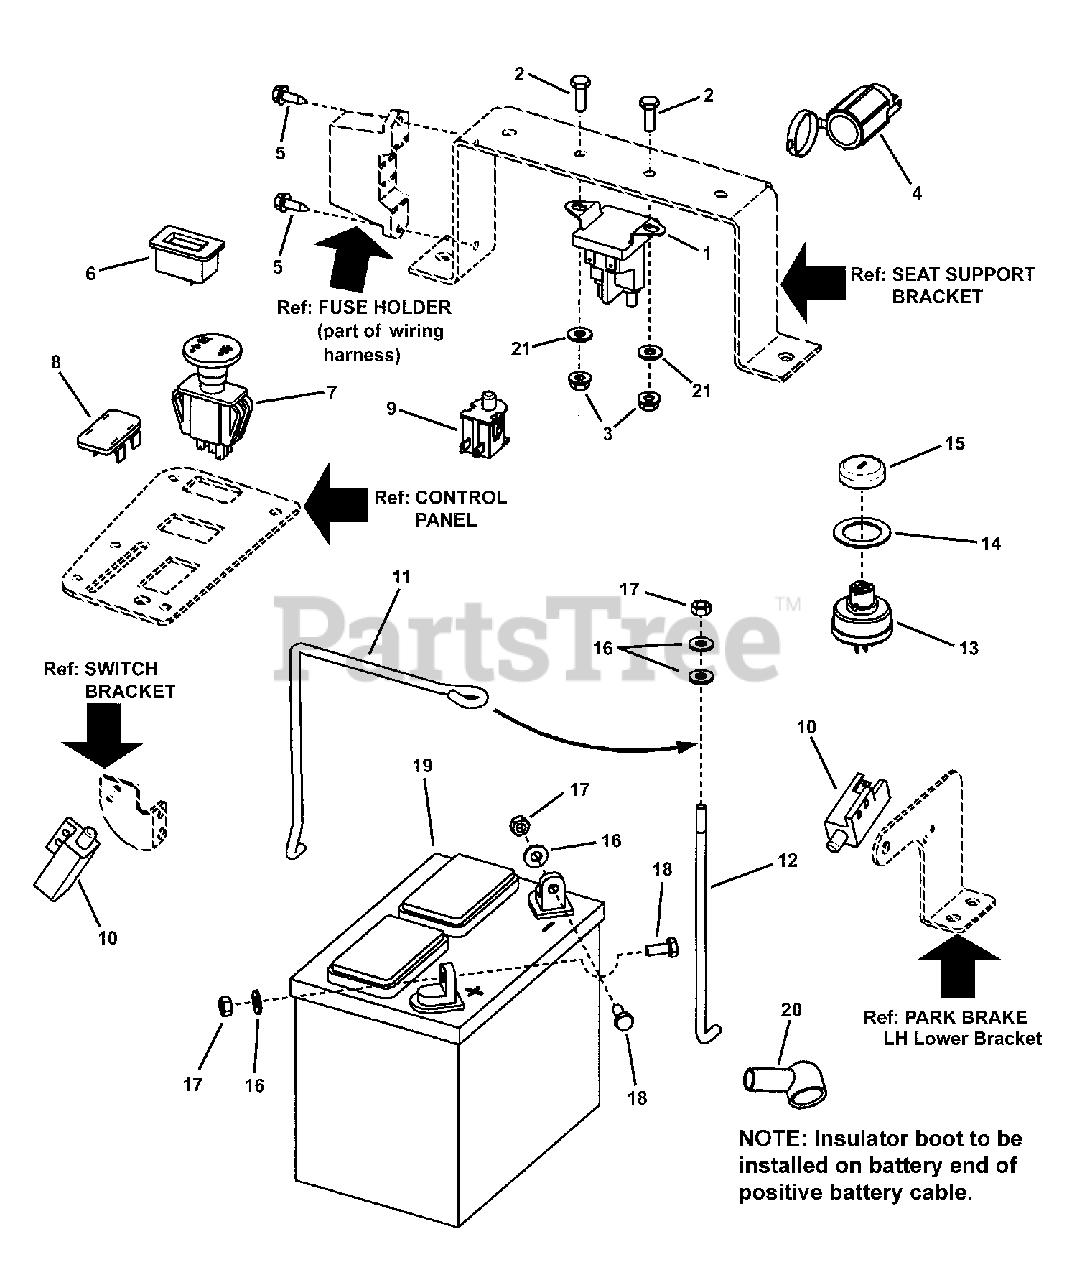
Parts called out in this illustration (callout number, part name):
1	SOLENOID, Super Trombetta, 2 TERM.
2	CAPSCREW, Hex Head, 1/4C X1 GR5 YZ
3	NUT, Hex Flange Lock, 1/4C YZ
4	POWER OUTLET, 12 Volt DC
5	CAPSCREW, Hex Head Flange Taptite, 1/4C X3/4 BZ
6	HOUR METER, Inductive
7	SWITCH, PTO, Yellow
8	PLUG-HOLE BLACK
9	SWITCH, Seat
10	SWITCH, DPDT
11	BRACKET, Battery
12	HOLD DOWN, Battery
13	SWITCH, Ignition
14	BUSHING, Mach, .875X1.375X.075ZP
16	WASHER, .28X.63X.065 YZ
17	NUT, Hex Center Lock, 1/4C GR5 BZ
18	CAPSCREW, Hex Head, 1/4C X5/8 GR5 ZP
19	BATTERY, 12 VOLT, 230 CCA
20	COVER, Battery Cable
21	WASHER, Lock, Internal Tooth, 1/4 YZ
